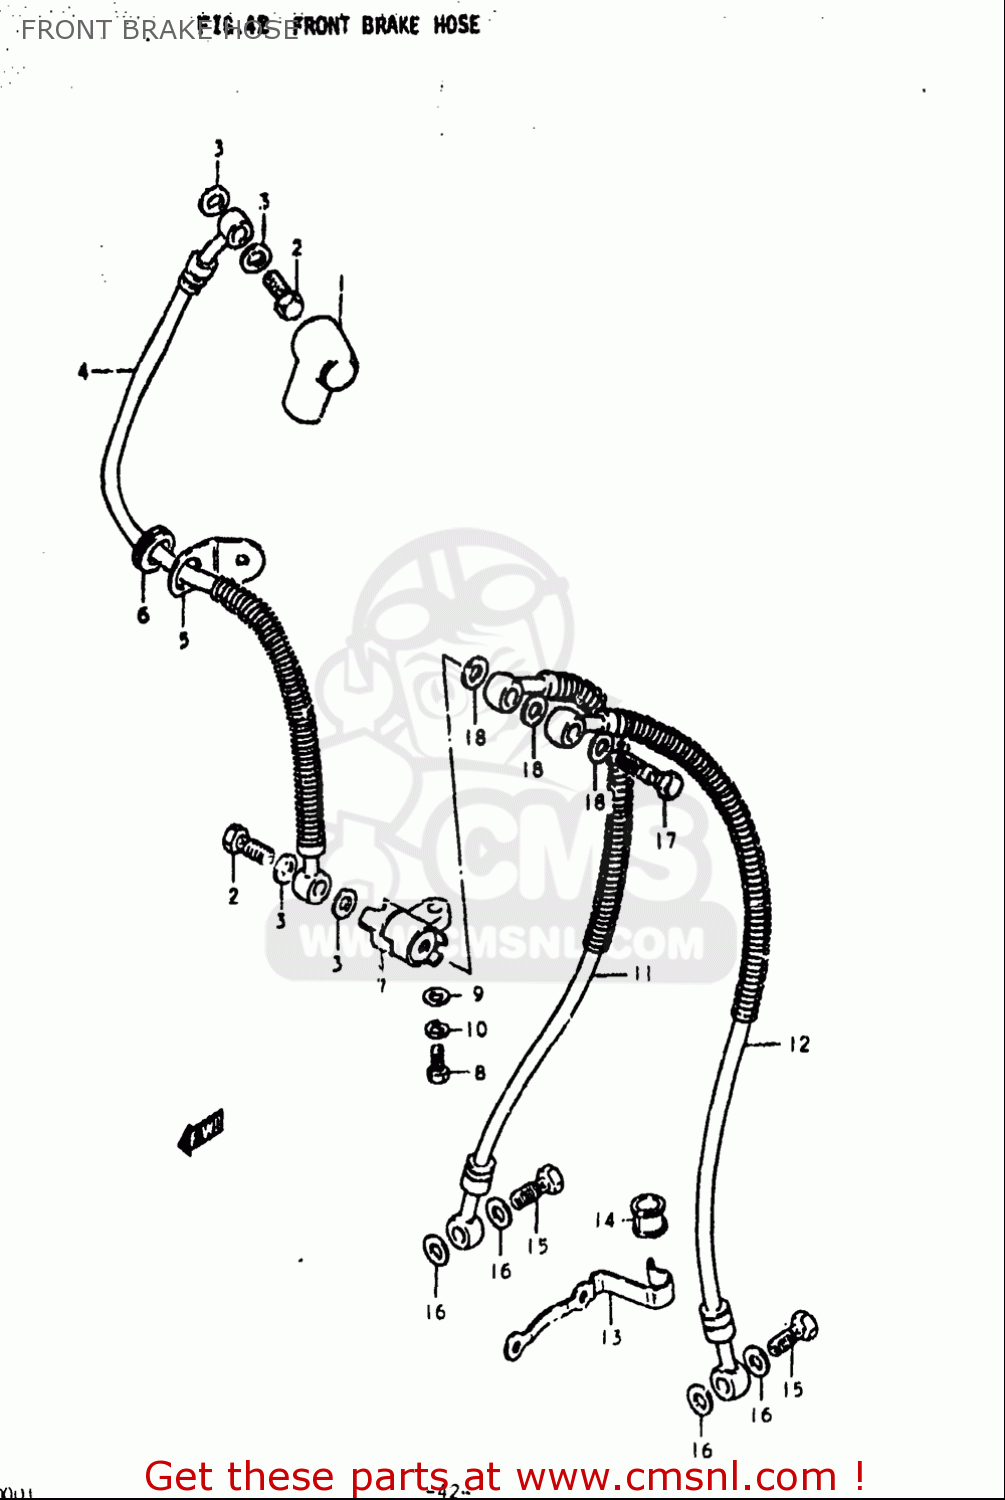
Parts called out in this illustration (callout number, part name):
1	BOOT,MASTER CYLINDER
2	BOLT UNION
3	WASHER(10X15X1.5)
4	HOSE,FRONT BRAKE NO.1
5	GUIDE,BRAKE HOSE
6	GROMMET
7	JOINT,BRAKE HOSE
8	BOLT
9	WASHER
10	WASHER,LOCK
11	HOSE,FR BRAKE NO.2,L
13	GUIDE,BRAKE HOSE NO.2
14	BUSH,BRAKE HOSE GUIDE,NO.2
15	BOLT UNION
16	WASHER(10X15X1.5)
17	BOLT UNION
18	WASHER(10X15X1.5)
